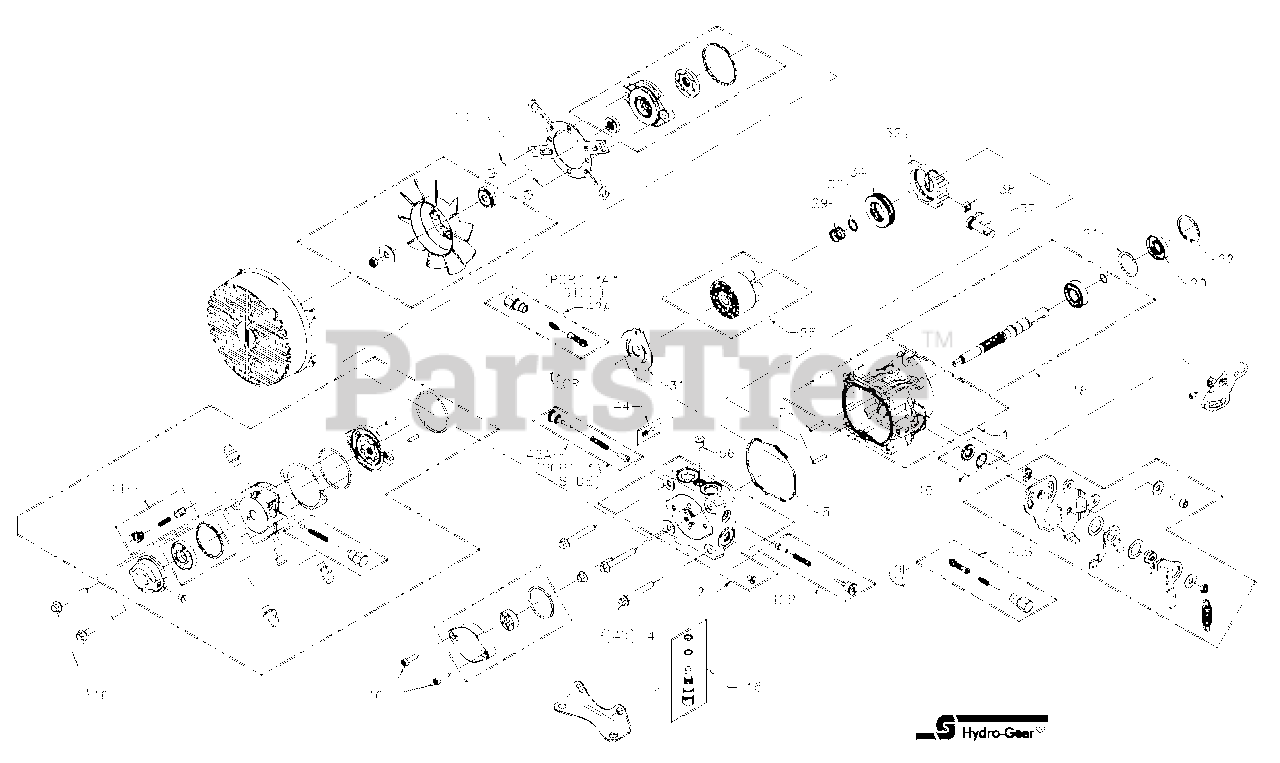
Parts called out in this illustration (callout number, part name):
1	Kit, Housing
2	Kit, End Cap W/PPT & STD
3	Pin, .219 x 1
4	Hex, Flange Bolt M8-1.25 x 60mm
5	Kit, Chg Pump
10	Screw, Cap M6 x 1 x 25
15	Kit, Bypass Valve
18	Kit, Pump Shaft 15mm Keyw
20	Seal, Lip 17 x 40 x 7
21	Washer 1.23 x 1.56 x .04
22	Ring, Ret 1.56 Int
25	Kit, 10 CC Block
29	Spring, Block
30	Washer, Thrust .59 x .78 x .04
31	Plate, Valve
32	Swashplate 10cc
34	Bearing, Thrust Ball 30 x 52 x 13
37	Arm, Trunnion 10 Cc
38	Guide, Slot
42	Kit, Shock Valve 200 Bar
44	Kit, Chg Relief
49	Kit, BDP-10l Seal
56	Plug 7/16-20 (Metal)
NS	Kit, Overhaul Seal
